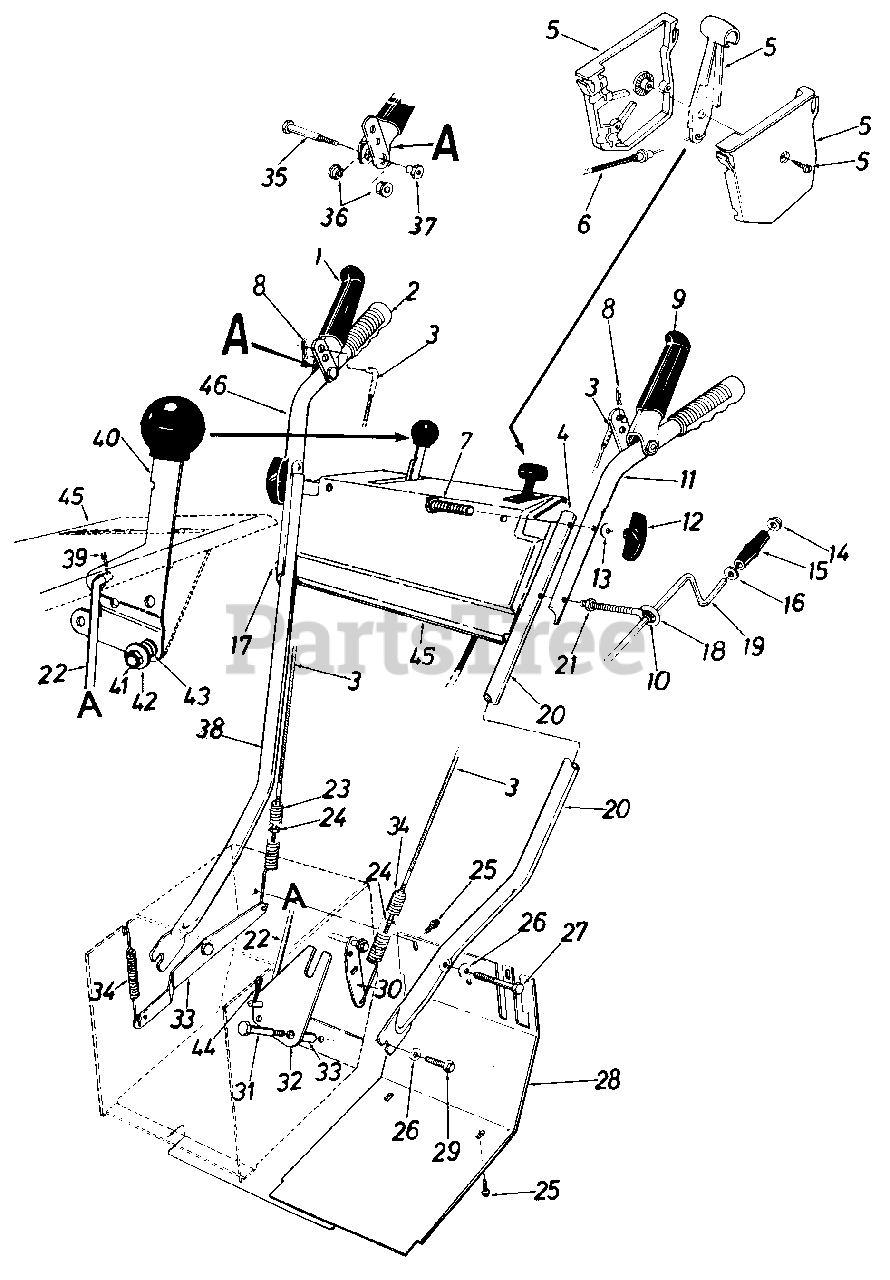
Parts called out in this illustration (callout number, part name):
1	Clutch Grip Ass'y. R.H.
2	Grip
3	Lockout Cable 30.5" Lg.
4	Plastic Plug
5	Throttle Control Box Ass'y.
6	Throttle Wire
7	Hex Scr. 5/16-18 x 2.00" Lg.
8	Hairpin Cotter
9	Clutch Grip Ass'y. L.H.
10	Chute Crank Grommet
11	Upper Handle Half L.H.
12	Hand Knob
13	Bell-Wash. .345" I.D. x .88" O.D. x .060
14	Cap Speed Nut for 3/8" Rod
15	Knob 3/8" Rod
16	Fl-Wash. .38" I.D. x .62" O.D. x .060
17	Carr. Bolt 5/16-18 x 2.50" Lg.
18	Eyebolt
19	Chute Crank Ass'y.
20	Lower Handle Half L.H.
21	Hex Nut 5/16-18 Thd.
22	Shift Rod
23	Ext. Spring .75" O.D. x 5.00" Lg.
24	Hex Ins. L-Nut 1/4-20 Thd.
25	Hex Wash. Hd. Self-Tap Scr. 5/16-24 x .50" Lg.
26	Bell-Wash. .401" I.D. x .88" O.D. x .060
27	Hex Scr. 3/8-16 x 2.00" Lg.
28	Frame Cover
29	Pilot Scr. 3/8-16 x .88" Lg.
30	Drive Clutch Brkt. Ass'y.
31	Shld. Bolt .498 Dia. x 2.005
34	Spring
35	Shld. Bolt .374" Dia. x 1.53" Lg.
36	Hex Flange Brg. Plastic .38" I.D.
37	Shld. Nut 1/4-20 Thd.
38	Lower Handle Half R.H.
40	Shift Handle Ass'y.
41	Hex Ins. Jam L-Nut 3/8-24 Thd.
42	Comp. Spring .60" O.D. x .88" Lg.
43	Bell-Wash. .401" I.D. x .88" O.D. x .060
44	Cotter Pin 3/32" Dia. x .75" Lg.
45	Handle Panel Ass'y.
46	Upper Handle Half R.H.
